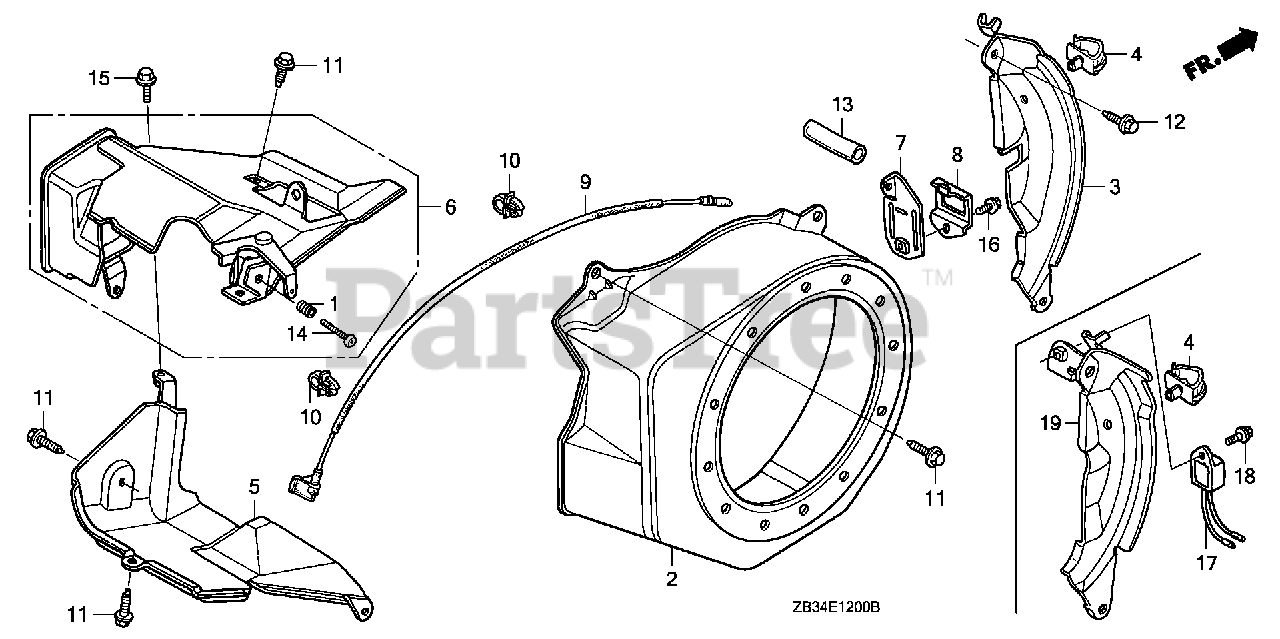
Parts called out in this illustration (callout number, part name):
1	SPRING, CONTROL ADJUSTING
2	COVER, FAN *NH1* (BLACK)
3	PLATE, SIDE (ALERT & LAMP)
3	PLATE, SIDE (LAMP)
4	CLAMP, CORD
5	SHROUD (LOWER)
6	SHROUD ASSY. (UPPER)
7	BASE, WIRE CLIP
8	COVER, WIRE CLIP
9	WIRE, STOP SWITCH (395MM)
11	BOLT, FLANGE (6X12) (CT200)
12	BOLT, FLANGE (6X20) (CT200)
13	TUBE, CORD
14	SCREW, PAN (5X35)
15	BOLT, FLANGE (6X8)
16	BOLT, FLANGE (6X8)
17	ALERT UNIT, OIL
18	BOLT, FLANGE (6X8)
19	PLATE, SIDE (ALERT & LAMP)
